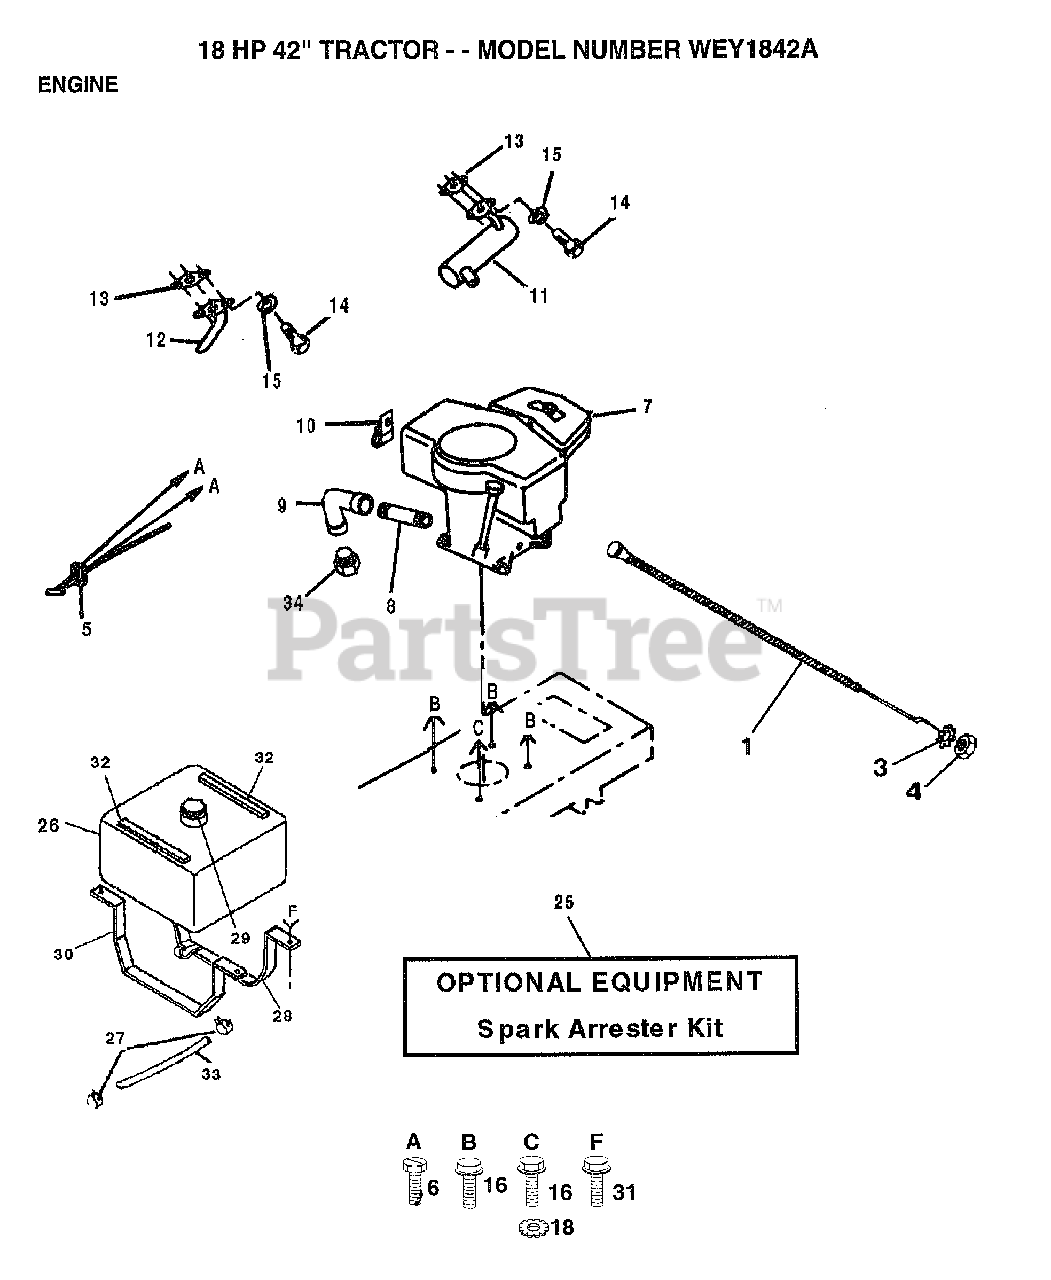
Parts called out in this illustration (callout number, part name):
1	CHOKE CONTROL
3	LOCKWASHER
6	SCREW LT
8	PIPE NIPPLE LT
9	ELBOW
10	CLIP T
12	EXHAUST TUBE T
15	LOCKWASHER
16	SCREW
18	LOCKWASHER
25	SPARK ARREST KIT
27	HOSE CLAMP
28	STRAP ASM. F.TANK
30	"STRAP,TANK"
31	SCREW LT
32	"STRIP,FORM"
33	HOSE T
